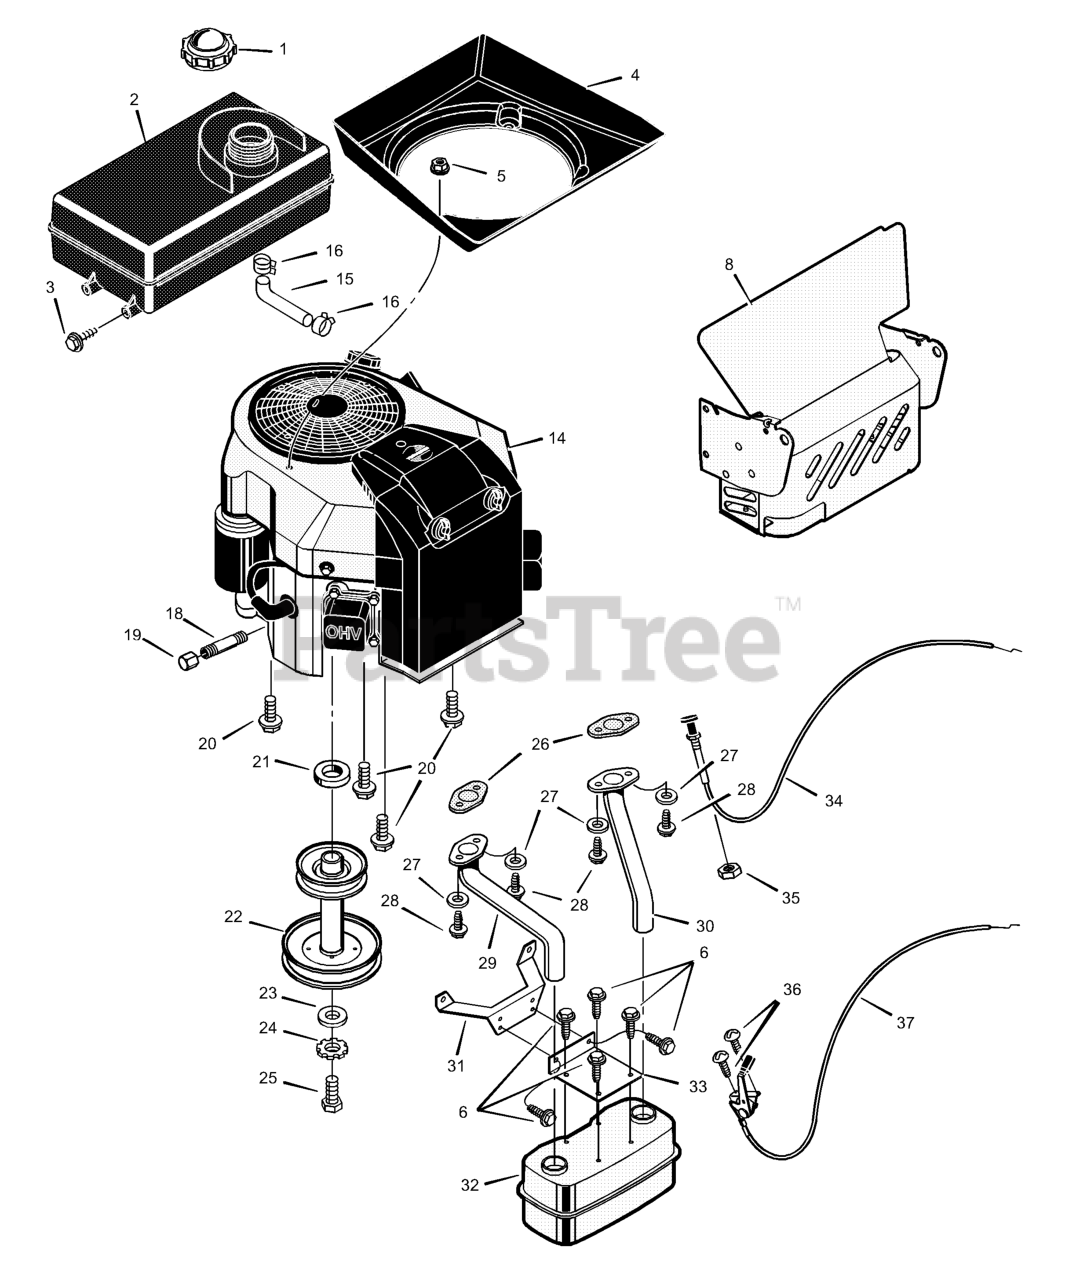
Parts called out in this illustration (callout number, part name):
1	Cap, Fuel
2	Tank, Fuel
4	Plenum, Air Intake
5	Nut
8	Shield, Heat
14	Engine *
15	Fuel Line (Must cut to length)
16	Clamp
18	Pipe, Oil Drain
19	Cap, Oil Drain
20	Bolt
22	STACK PULLEY ASSEMBLY
24	Lockwasher
27	Washer
28	Bolt
29	Tube, Right Exhaust
30	Tube, Left Exhaust
31	Bracket, Muffler Mount
32	Muffler
33	Bracket, Muffler
35	Nut
37	Control, Throttle
